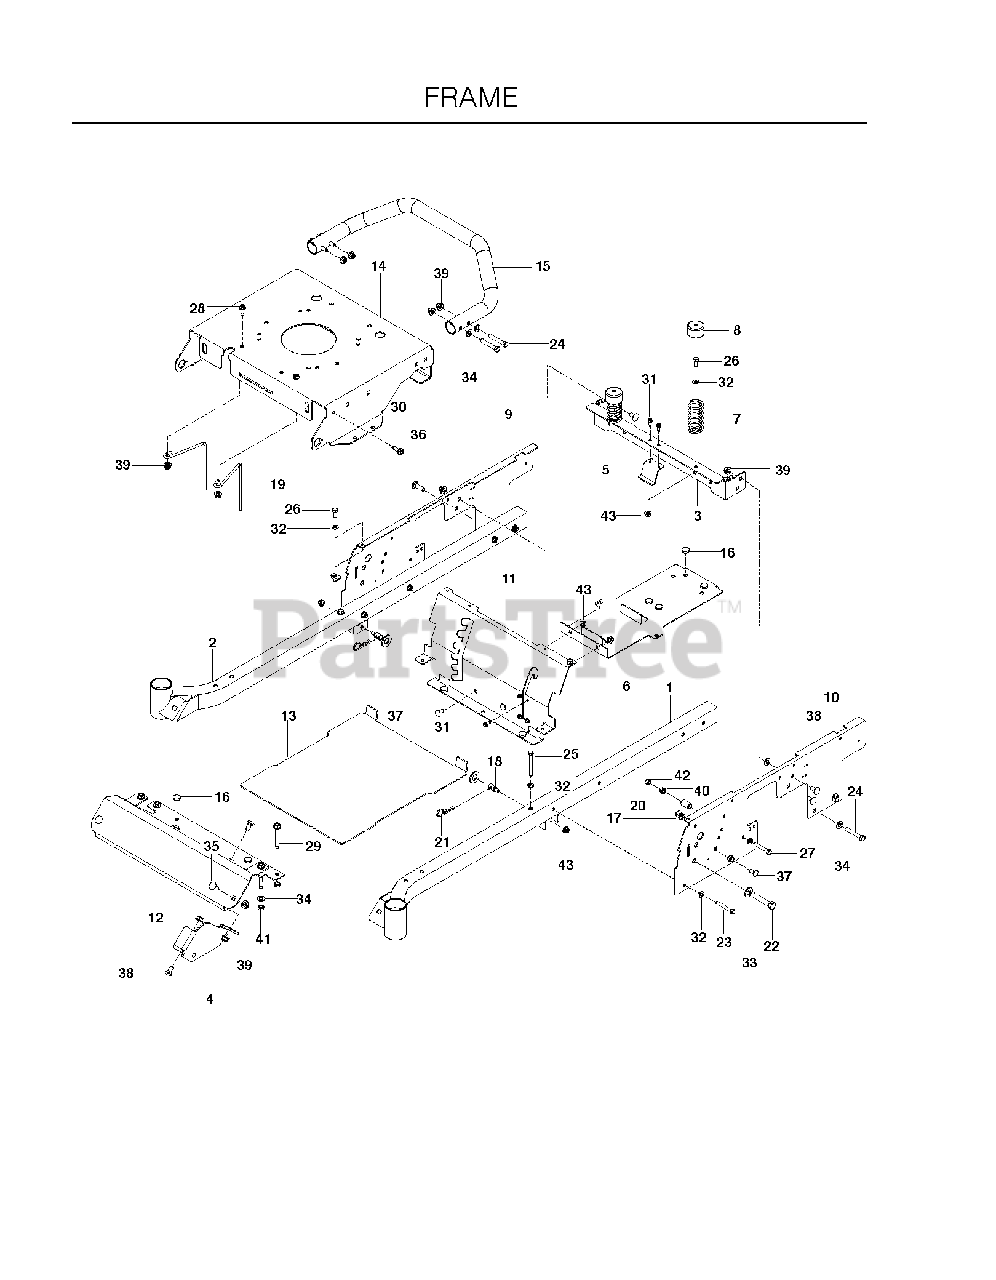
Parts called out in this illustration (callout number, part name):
1	WLDMT, FRAME TUBED, LH YLW
2	WLDMT, FRAME, TUBE RH YLW
3	SUPPORT, REAR SEAT, YLW
4	BRACKET, FRONT DECK, BLK
5	HOLDING DEVICE, FUEL TANK, BLK
6	SUPPORT, TANK/BATT, BLK
7	SEAT SPRING
8	SPRING CAP
9	PANEL, RH SIDE, YLW
10	PANEL, LH SIDE, YLW
11	PANEL, SEAT SUPP. YLW
12	FOOT, REST, YLW
13	PLATE, FOOT W/DECALS, HUS
14	PLATE, ENGINE, YLW
15	IMPACT BAR, YLW
16	GROMMET, BUMPER
17	U-CLIP 5/16-18 NUT RETAINER
18	STUD.FASTNER.W/ANTI-ROTATE
19	BELT GUIDE
21	HAIRPIN #4
22	HCS 1/2C X 2 3/4
23	CAPSCREW
24	HCS 3/8C X 2 1/4
25	HCS 5/16C X 2-3/4
26	HCS 5/16C X 3/4
27	HCS 5/16-18X2
28	BOLT 3/8-16 X 1.0
29	ENGINE BOLT, SPECIAL
31	SCREW 1/4 X 5/8
32	FLAT WASHER 5/16 SAE
33	WASHER 1/2" FLAT
34	WASHER 3/8 SAE FLAT
35	RHSNB 3/8C X 1
36	RHSNB 3/8-16 X 1-1/4
37	BOLT 5/16C X 3/4" CARRIAGE
38	RHSNB 3/8-16 X 3/4 GR5 ZD
39	NUT 3/8-16 HEX FLG NYLOC ZD
40	NUT 5/16C WHIZ
41	NUT HEX 3/8-16 NYLON, THIN
42	NUT 5/16 NYLOC
43	5/16-18 NYLOC FLANGE NUT
